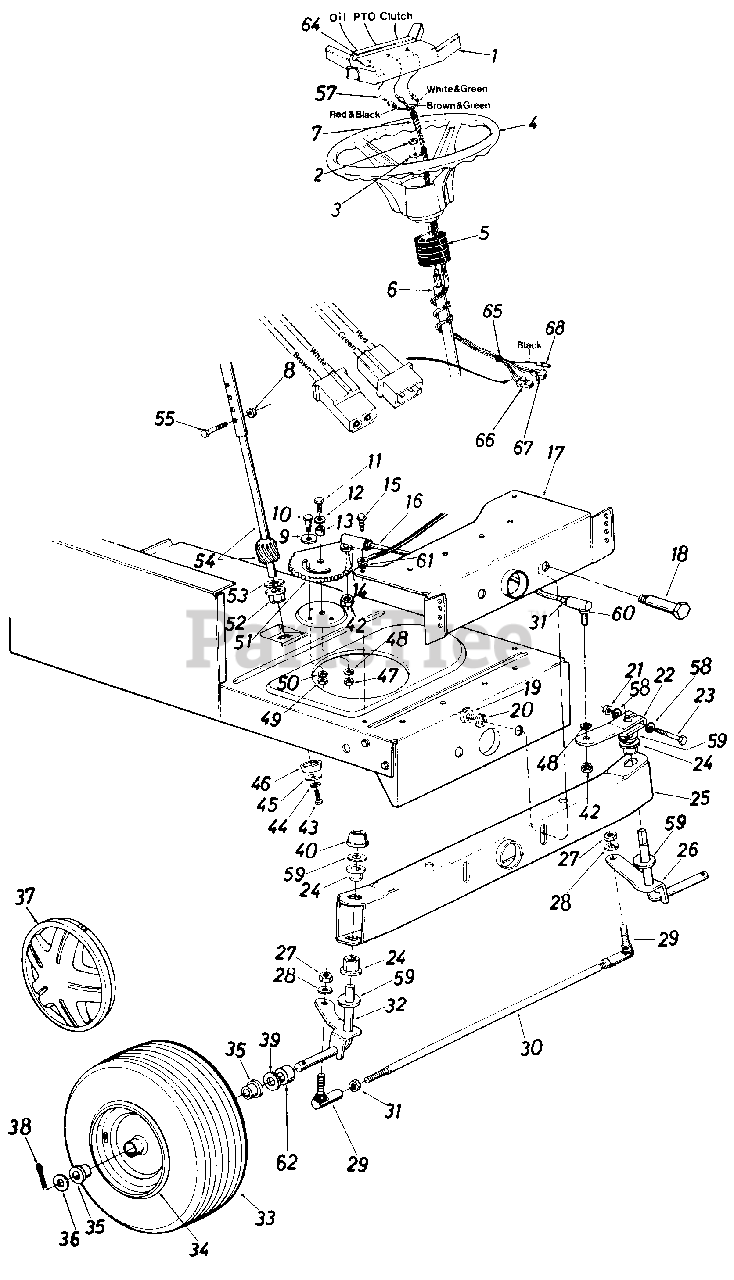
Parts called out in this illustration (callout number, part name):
1	Steering Wheel Insert
2	Hex L-Nut 5/16-24 Thd.
3	Belleville Wash. .345" I.D.
4	Steering Wheel
5	Steering Bellow
6	Steering Column Ass'y.
7	Wire Harness
8	Hex L-Nut 1/4-20 Thd.
9	Fl-Wash. .438" I.D. x 1.37"
10	Shoulder Bolt .437" Dia. x .35" Lg. 5/16-18 Thd.
11	Hex Bolt 3/8-24 x 1.0" Lg.(Grade 5)
12	Bell-Wash. .40" I.D. x 1.13"
13	Spacer .380" I.D. x .625" O.D. x .227"
14	L-Wash. 3/8" I.D.
15	Hex Wash. Hd. Self-Tap Scr.
16	Steering Drag Link
17	Front Pivot Brkt.
18	Shoulder Bolt .498" Dia. x 2.04" Lg. 3/8-16 Thd.
19	Hex Nut 3/8-16 Thd.
20	L-Wash. 3/8" I.D.
21	Hex Cent. L-Nut 5/16-24 Thd.
22	Steering Arm Front Axle
23	Hex Bolt 5/16-24 x 2.00" Lg.(Grade 5)
24	Hex Flg. Brg. .634" I.D.
26	Front Axle Ass'y.-L.H.
27	Hex Nut 3/8-24 Thd.
28	L-Wash. 3/8" I.D.
29	Ball Joint 3/8-24 Thd.
30	Tie Rod
31	Hex Jam Nut 3/8-24 Thd.
32	Front Axle Ass'y.-R . H .
33	Wheel Ass'y. Comp.
34	Front Wheel Rim Only
35	Needle Bearing
36	Fl-Wash. .635" I.D. x 1.59 O.D.
37	Hub Cap
38	Cotter Pin 1/8" Dia. x 1.25" Lg.
39	Fl-Wash. .640" I.D. x .24" O.D.
40	Push Cap 5/8" Dia. Rod
42	Hex Jam Nut 3/8-24 Thd.
43	Hex L-Bolt 5/16-18 x .62"
44	L-Wash. 5/16" I.D.
45	Fl-Wash. .33" I.D. x 1.25" O.D.
46	Spacer (Plastic)
47	Hex Nut 3/8-24 Thd.
48	L-Wash. 3/8" I.D.
49	Hex Nut 5/16-18 Thd.
50	L-Wash. 5/16" I.D.
51	Steering Gear Segment
52	Hex Flg. Brg. .634 I.D.
53	Fl-Wash. (Hardened)
54	Steering Shaft Lower
55	Hex Bolt 1/4-20 x 1.31" Lg.
57	Bulb
58	Wave Wash. .32" I.D. x .62"
59	Fl-Wash. (Hardened)
60	Drag Link Ball Joint 3/8-24 Thd.
61	Ext. L-Wash. 5/16" I.D.
62	Spacer.635" I.D.
64	Steering Wheel Insert Label
65	Clamp
66	Connector
67	Connector
68	Connector
